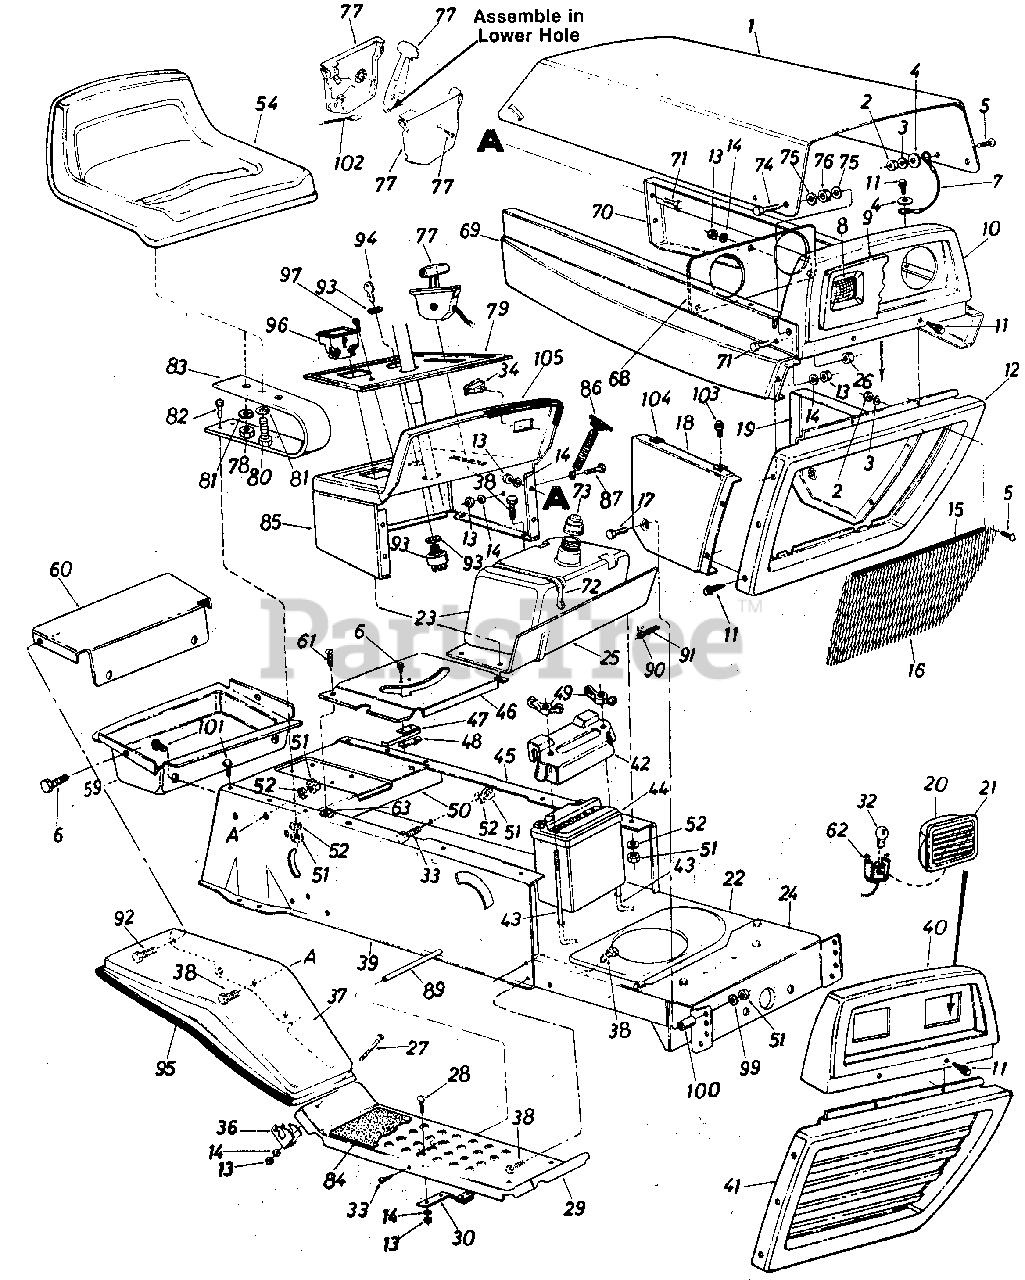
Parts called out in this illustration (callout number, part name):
3	L-Wash. #10 I.D.
4	Fl-Wash. .25" I.D. x .62"O.D.
5	Truss Scr. #10-24 x .375"
6	Truss Hd. Scr. #10-24 x .50" Lg.*
7	Hood Stop
8	Headlight
9	Headlight Bezel
10	Front Grille Upper Ass'y.
11	Hex AB-Tap Scr. #10 x .50"
12	Lower Grille
13	Hex Nut 1/4-20 Thd.
14	L-Wash. 1/4" I.D.
15	Vinyl "U"-Channel
16	Grille Screen
17	Hex Bolt 5/16-18 x 1.50"*
18	R.H. Lower Side Panel
19	L.H. Lower Side Panel
20	Headlight Housing
21	Headlight Lens
22	Lower Frame
23	Fuel Tank
24	Front Pivot Brkt.
25	Fuel Tank Support
26	Hex Cent. L-Nut 3/8-16 Thd.
27	Truss Hd. Scr. 1/4-20 x 1.75"*
28	Carriage Bolt 1/4-20 x .62"*
29	Running Board
30	Blade Brake Ass'y.
32	Head Lamp
33	Truss Mach. Scr. 5/16-18 x .75" Lg.*
34	Light Switch
36	Fender Clamp
39	R.H. Side Frame
40	Front Upper Grille Ass'y.
43	Battery Hold Down Rod
44	12-V Battery
45	L.H. Side Frame
46	Transmission Panel
47	Reverse Safety Switch
48	Insulator Nut Plate
49	Wing Nut 1/4-20
50	Hitch Plate
51	Hex Nut 5/16-18 Thd.
52	L-Wash. 5/16" I.D.
54	Seat Ass'y.
59	Tool Tray
62	Head Lamp Socket
63	Speed Nut #10Z
68	Head Lamp Retainer
69	Side Panel-R.H.
70	Side Panel-L.H.
71	Hex Bolt 1/4-20 x .62" Lg.
72	Tie Strap
73	Fuel Cap Gauge
74	Hex Bolt 3/8-16 x 1.00" Lg.
75	Fl-Wash. .380" I.D. x 1.00"O.D.
76	RubberWash. .33" I.D. x .87" O.D.
77	Throttle Control Box Ass'y.
78	Hex Nut 1/2-13 Thd.
79	Dash Panel Insert
80	Hex Bolt 1/2-13 x 1.00" Lg.
81	L-Wash. 1/2" I.D.
82	Hex Bolt 5/16-18 x 1.00"*
83	Seat Spring
84	Foot Pad
87	Hex Bolt 1/4-20 x .50" Lg.
89	Running Board Rod
90	Hose Clamp
91	Fuel Line
92	Thread Rolling Scr. 1/4-20 x .50" Lg.
93	Ignition Switch
94	Ignition Key
95	Trim Strip
96	Ammeter
97	Hex "AB"-Tap Scr. #8 x .50" Lg.
99	Belleville Wash. .34" I.D.
100	Spacer.344" I.D. x 1.0" O.D. x .75" Lg.
101	Hex Wash. Hd. AB-Tap Scr. 5/16 x .75" Lg.
102	Throttle Control Wire
103	Hex Wash. Hd. Self-Tap Scr.
104	Speed Nut #10Z
105	Trim Strip-15"
